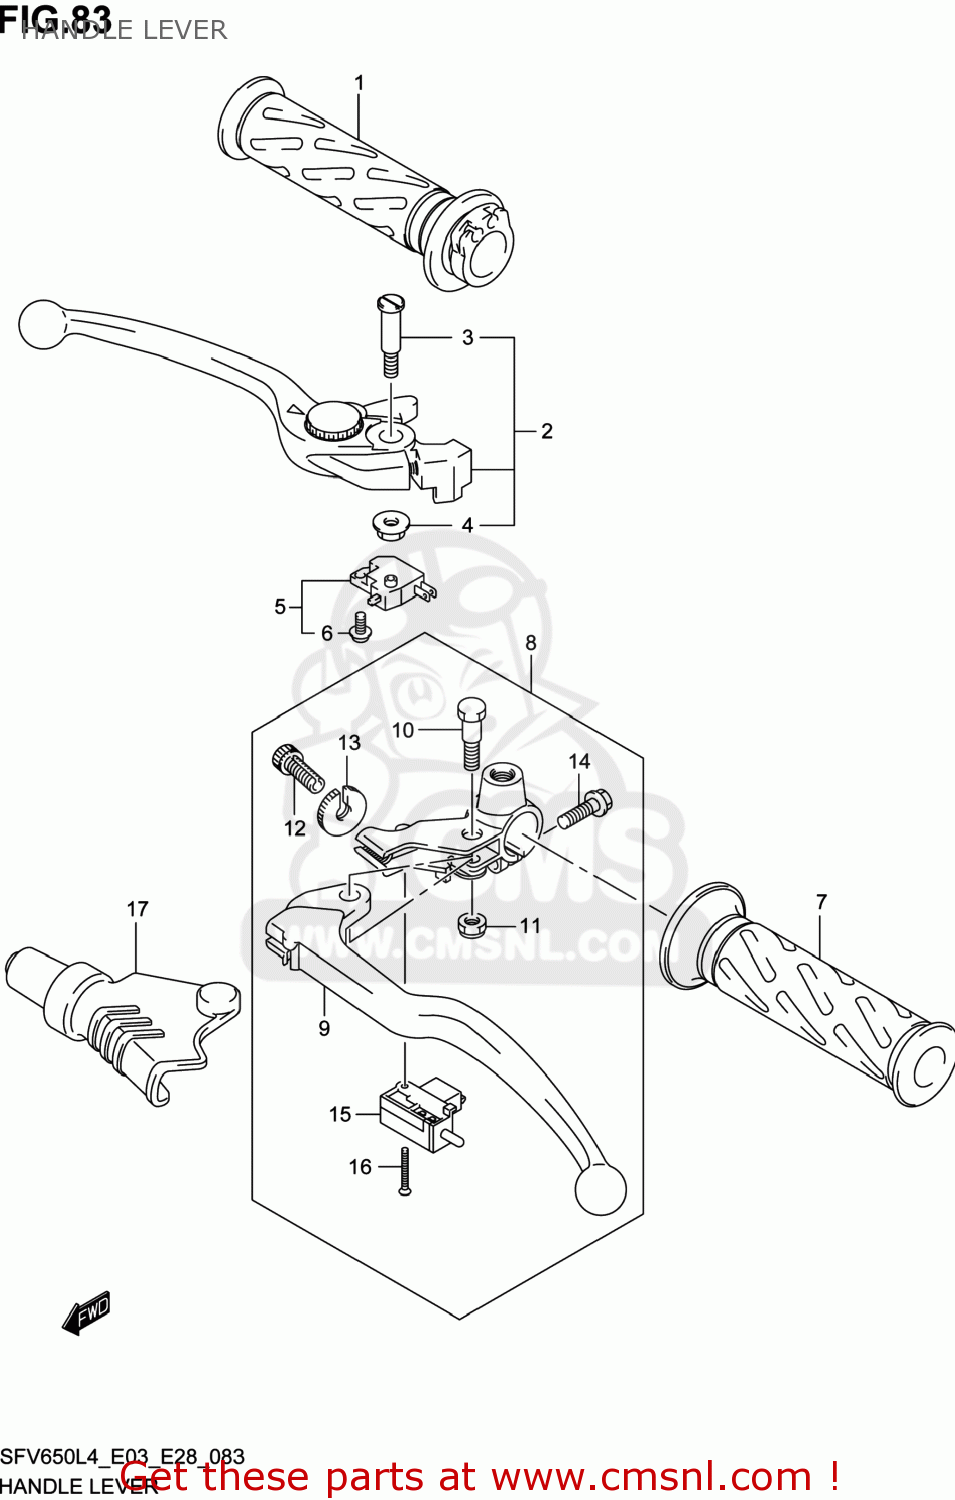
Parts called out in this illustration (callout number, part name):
1	GRIP,THROTTLE
2	LEVER ASSY,FR BRAKE
3	BOLT,LEVER PIVOT
4	NUT
5	SWITCH ASSY,FR BRAKE
6	SCREW
7	GRIP,L
8	LEVER ASSY,CLUTCH
9	LEVER,CLUTCH
10	BOLT,LEVER PIVOT
11	NUT
12	ADJUSTER,WIRE
13	NUT,LOCK
14	BOLT
15	SWITCH,CLUTCH
16	SCREW
17	COVER,CLUTCH LEVER
